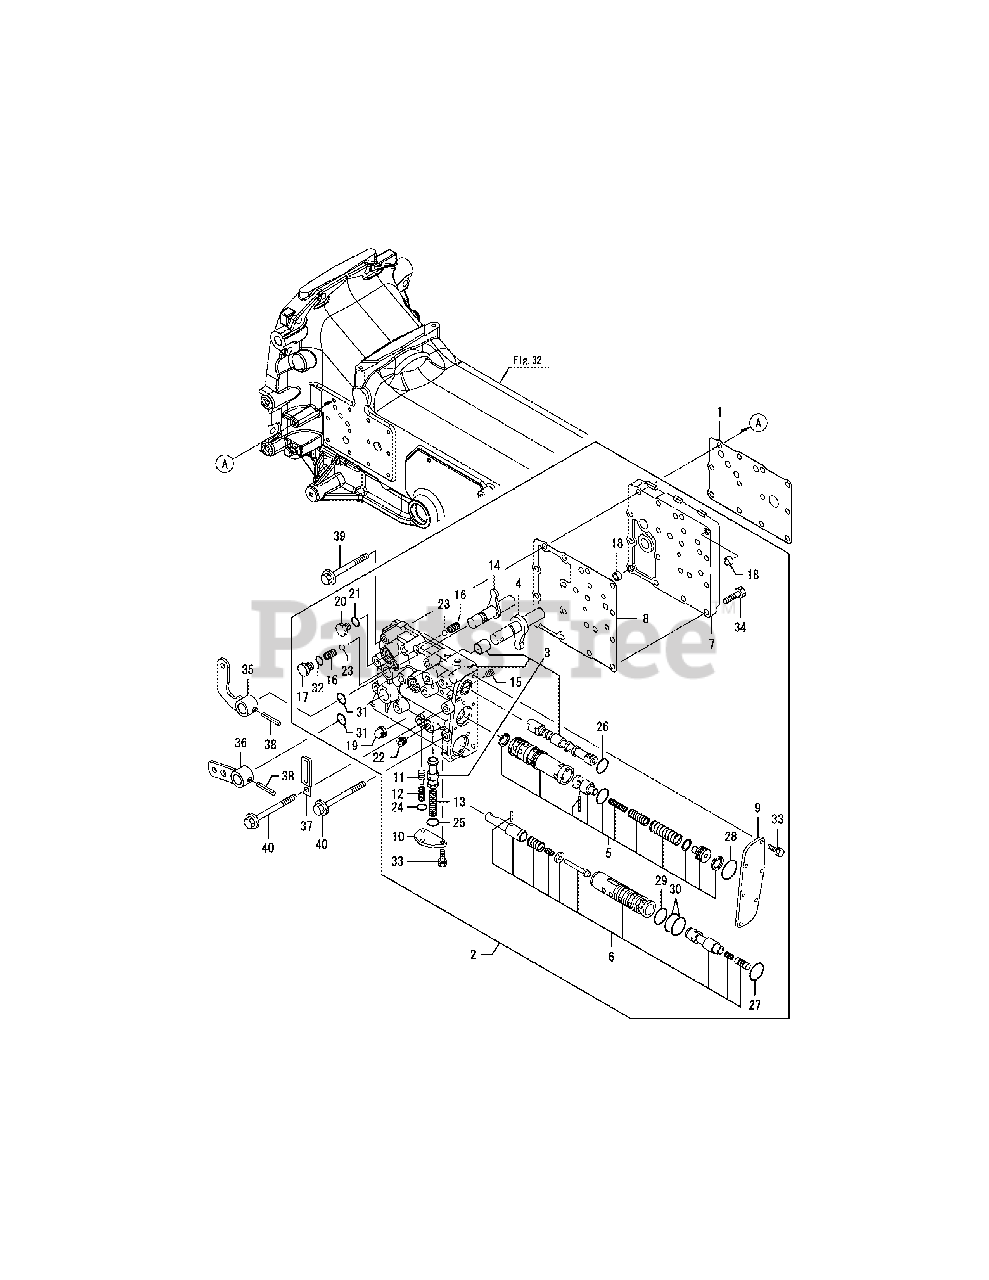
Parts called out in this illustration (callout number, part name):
1	GASKET, PR VALVE
2	VALVE ASSY, REVERSE
4	ARM CLUTCH,CMP
6	CLUTCH VALVE CMP
8	GASKET, VALVE CASE
12	SPRING, RELIEF
13	SPRING, CUT-OF
17	PLUG 1/2-20 UNF
22	PLUG PT1/8,SCREW
23	BALL 5/16, STEEL
24	O-RING 1A P-12.5
25	O-RING 1A P-18.0
26	O-RING 1A P-22.0
27	O-RING 1A P-29.0
28	O-RING 1A P-32.0
29	O-RING, 1A S22.0
30	O-RING 1A S-22.4
31	O-RING, 1A 19014
32	PACKING 1A AS 905
37	CLAMP, WIRE HARNESS
38	SPRING PIN 6X36
39	BOLT M 8X 80 PLATED
40	BOLT M 8X 95 PLATED
